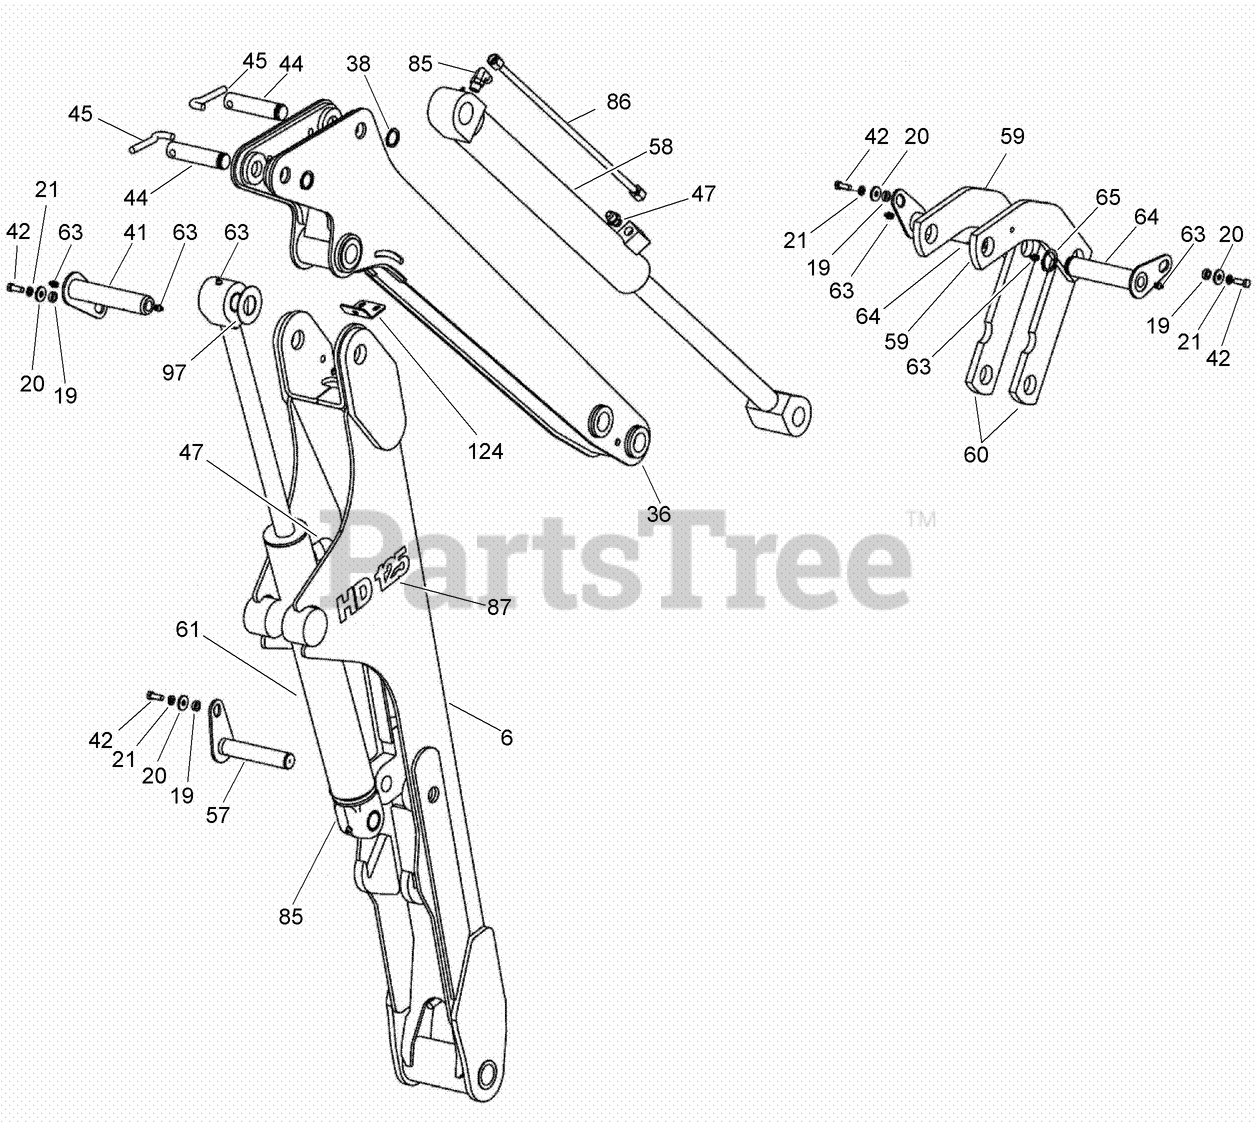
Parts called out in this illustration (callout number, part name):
6	ASM-Boom
21	WASHER-Spring Lock, Reg 3/8 ZND
36	DIPPER ASM-Backhoe
38	RING-RETAINING
41	PIN-RETAINING
42	BOLT-Hex, 3/8 NC x 1-1/4 inch
45	PIN-RETAINER
47	CONNECTOR-Str Thd 1/2, 37FL-ORB 1/2
57	PIN-DIPPER CYLINDER TO BOOM
58	HYD CYLINDER ASM (BUCKET)
59	LINK-Curved, Dipper to Bucket
60	LINK-Straight, Dipper to Bucket
61	CYLINDER-76 (3) ID x 498 mm (19-5/8 inch) Stroke, Dipper
63	FITTING-Lube 1/8-27 Dryseal PTF
85	ELBOW-90 DEG
86	TUBE-Hydraulic, Bucket
87	DECAL-HD125
124	BRACKET-Boom End, Hose
